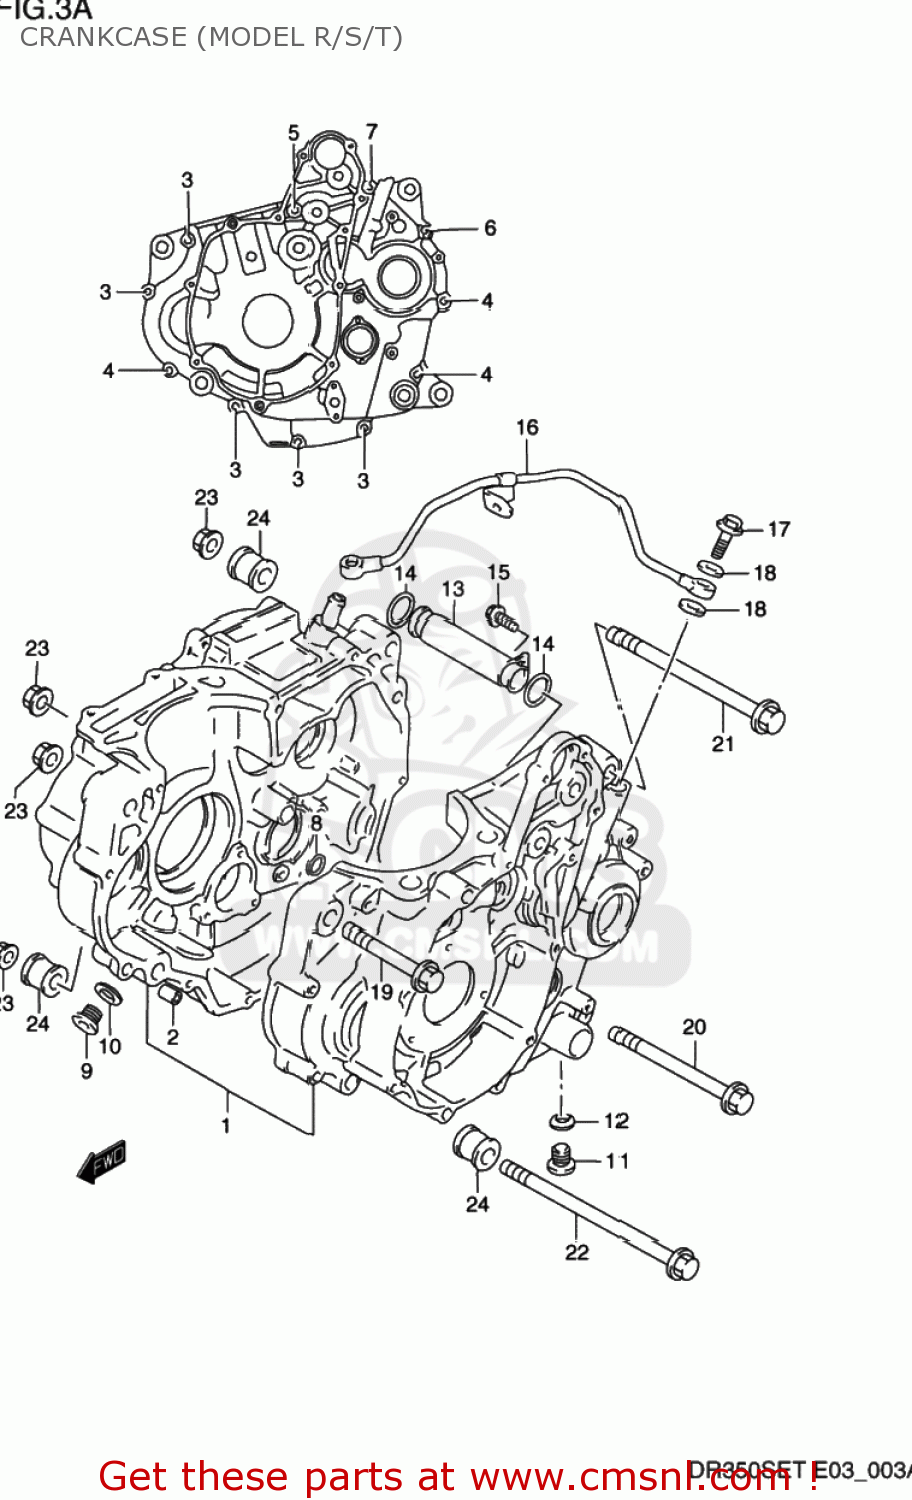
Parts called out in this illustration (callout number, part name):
1	CRANKCASE SET
2	PIN
3	BOLT
4	BOLT
5	BOLT
6	BOLT
7	BOLT
8	O-RING
9	PLUG,14X12
10	GASKET(13.8X18.8X4.8) (NAS)
11	BOLT
12	GASKET(12.1X16.2X3.7) (NAS)
13	PIPE,T/M OIL INNER
14	O RING(D:2.4,ID:15.8)
15	BOLT
16	PIPE,TRANSMISSION OIL,OUTER
17	BOLT UNION
18	GASKET 8.2X14X1 (NAS)
19	BOLT 10X85
20	BOLT(10X101.5)
21	BOLT(10X115)
22	BOLT(10X143)
23	NUT
24	SPACER,ENGINE MOUNTING
